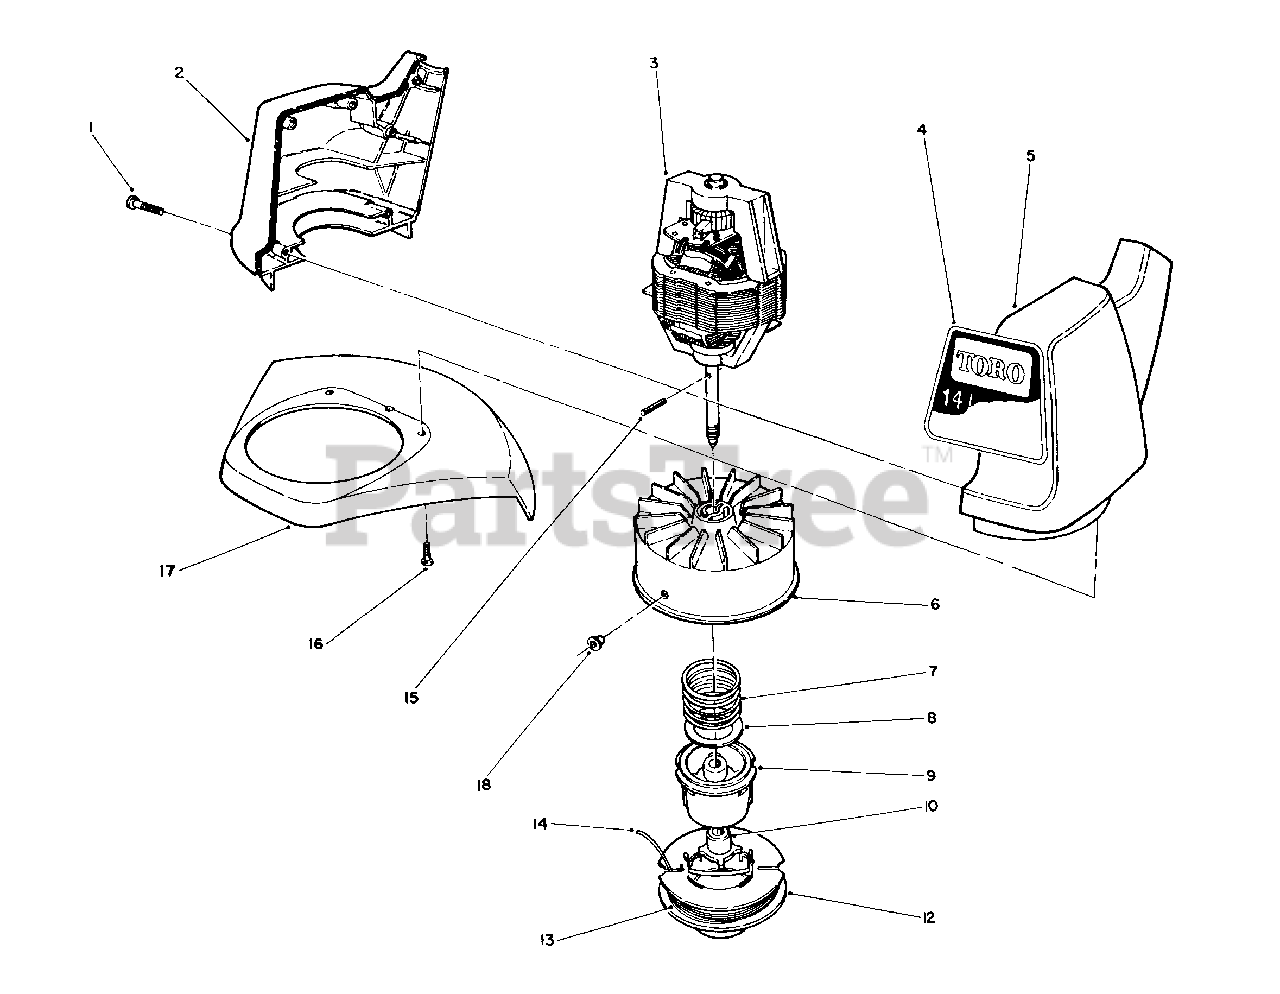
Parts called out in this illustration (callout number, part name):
1	Screw-Thread Forming
2	Housing-Motor R.H.
3	Motor-Electric
4	Decal-14"
5	Housing-Motor L.H.
6	Drum & Eyelet Assembly
7	Spring-Compression
9	Spool-Core
12	Spool-Empty
13	50' Coil-.065" Dia. Cutting Line Prewound on Spool
14	50' Coil-.065" Dia Cutting Line in Coil
15	Pin-Spiral
16	Screw-Thread Forming
17	Shield Assembly
